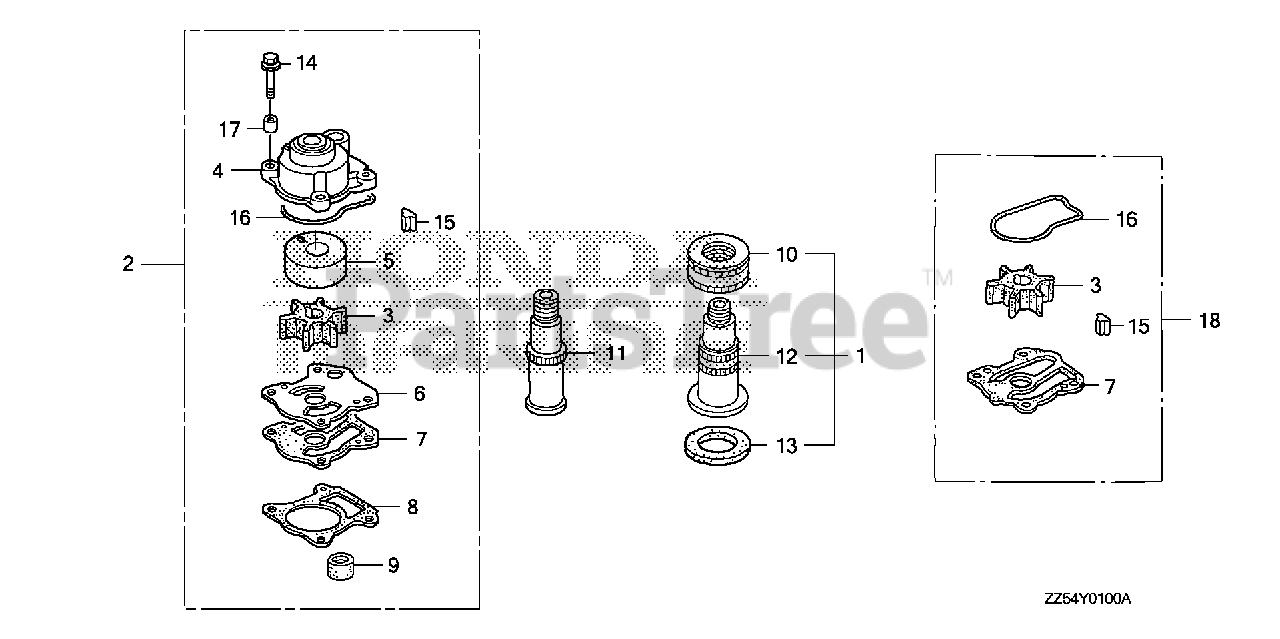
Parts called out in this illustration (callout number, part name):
2	PUMP KIT, IMPELLER (INCLUDES IMPELLER HOUSING)
3	IMPELLER, PUMP
4	HOUSING, IMPELLER
5	LINER, PUMP
6	COVER, IMPELLER
7	GASKET B, IMPELLER
8	GASKET, WATER PUMP
9	RING, WATER TUBE SEAL
11	JOINT, WATER HOSE
14	BOLT-WASHER (6X40)
15	KEY, WOODRUFF
16	O-RING, WATER PUMP
17	COLLAR, IMPELLER HOUSING
18	PUMP KIT, IMPELLER
